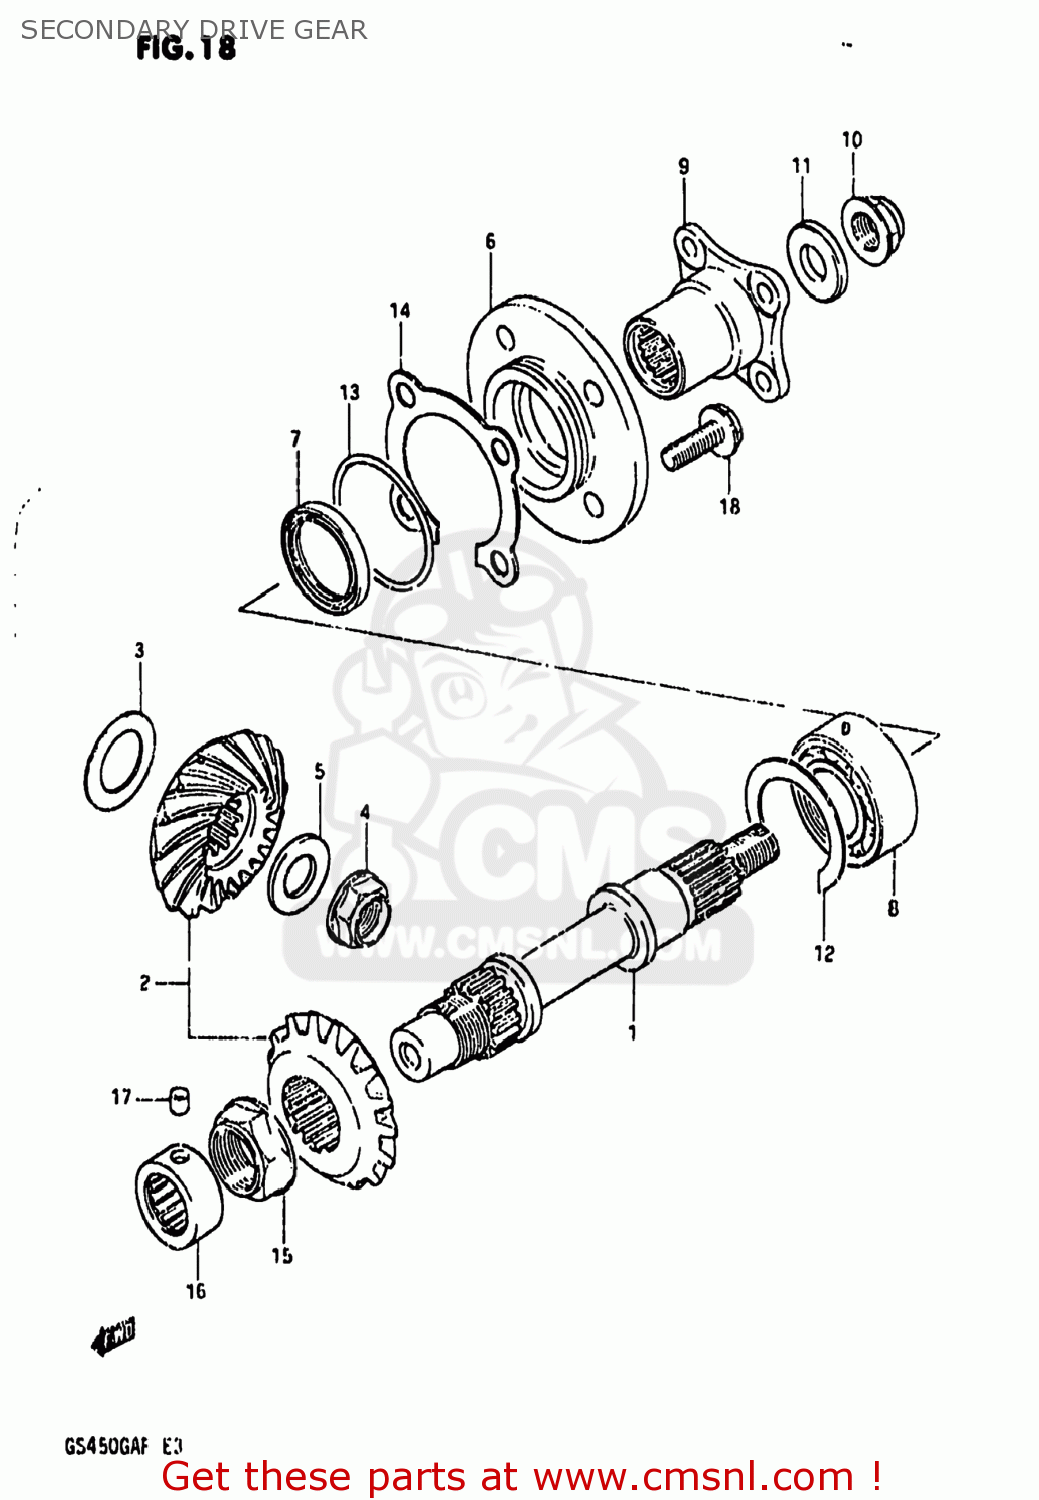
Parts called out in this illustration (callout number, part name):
1	SHAFT,SECONDARY DRIVEN
3	SHIM,SECONDARY DRIVE BEVEL
4	NUT
5	WASHER(16X30X3)
6	HOUSING,SECONDARY DRIVE
7	SEAL,OIL(32X42X7)
8	BEARING(25X52X21)
9	FLANGE,UNIVERSAL JOINT
10	NUT
11	WASHER(14X29X4)
12	SHIM,DRIVEN GEAR HOUSING
13	O-RING
14	SHAFT,SECONDARY DRIVEN,FRONT
15	NUT
16	BEARING(20X34X16)
17	PIN
18	BOLT
